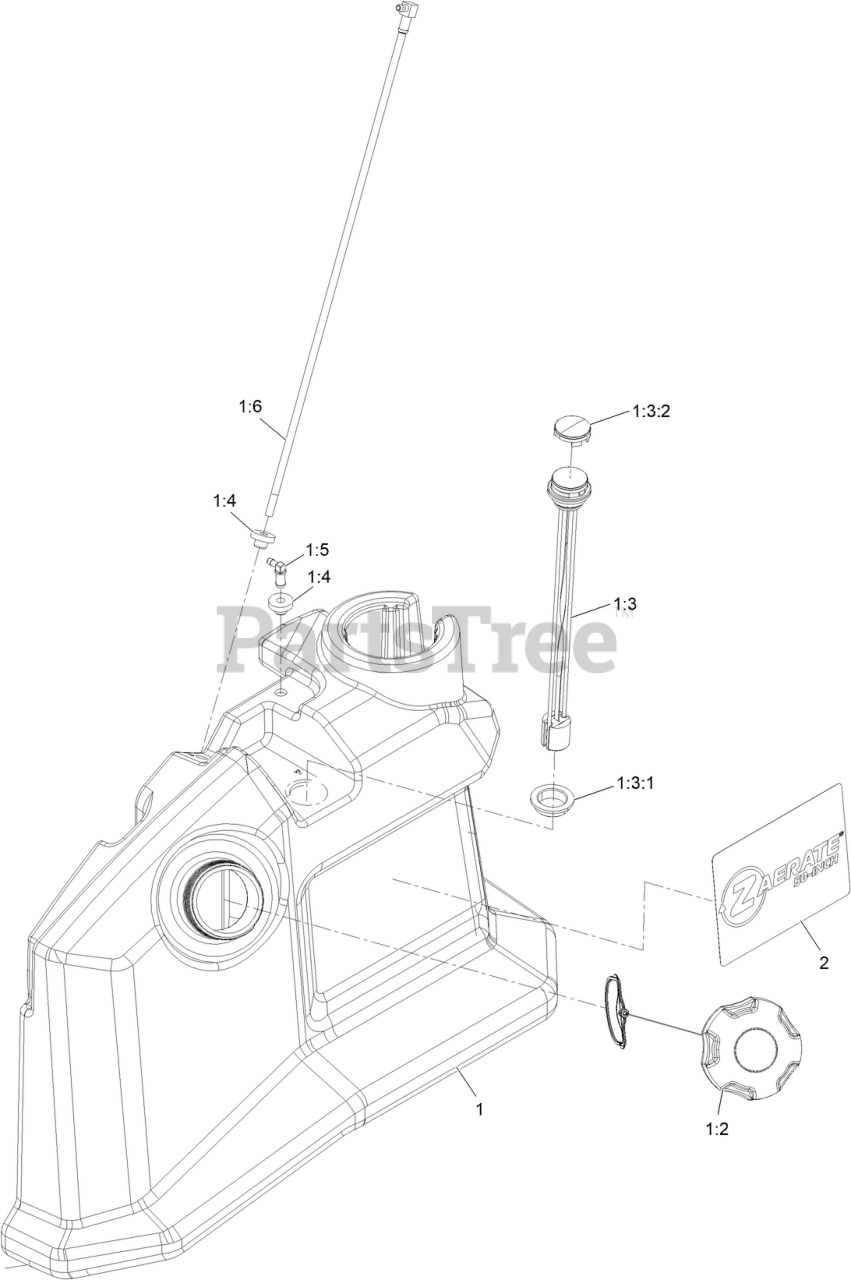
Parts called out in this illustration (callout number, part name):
1	Fuel Tank ASM
1:2	CAP-FUEL, RATCHETING
1:3	GAUGE-FUEL
1:3:2	Dial-Gauge
1:4	BUSHING
1:5	FITTING-PLASTIC
1:6	Fuel Tube ASM
2	DECAL-Z-AERATE-50-INCH
